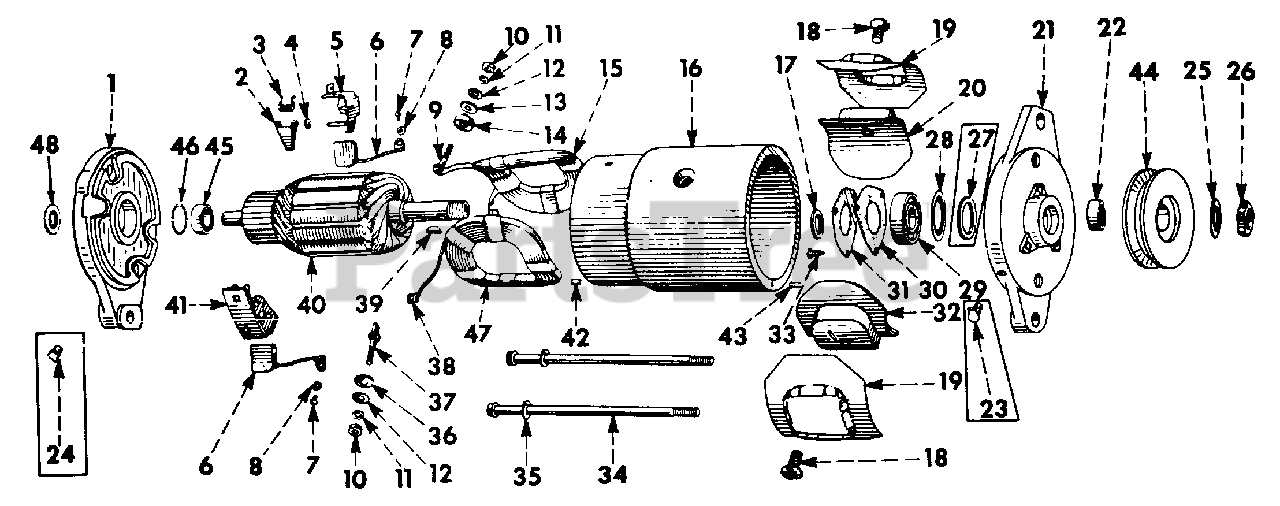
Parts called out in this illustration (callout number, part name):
1	Frame Assy, Commutator End
3	Spring, Brush
4	Washer, Brush Arm Space
5	Holder, Brush Ground
6	Brush
7	Screw, No. 6 X 1/4 C-Z Slt Rd Hd Mach
7	Screw, No. 6 X 5/16 C-Z Slt Rd Hd Mach
8	Washer, Brush Lead Attaching Screw Lock
9	Stud, Terminal Field
10	Nut, No. 12 C-Z
11	Washer, Field Terminal Stud Lock
12	Washer, Terminal Stud
13	Washer, Terminal Stud Insulating
14	Bushing, Field Terminal Insulating
14	Bushing, Field Terminal Insulating Inside
15	Coil, Field
16	Frame
17	Collar, Drive End Spacer - Inside
18	Screw, Pole Shoe
19	Insulator, Field Coil
20	Shoe, Pole
21	Frame, Drive End
22	Collar, Drive End Space
23	Not used in this application
24	Not used in this application
25	Washer, Drive End Shaft Nut Lock
26	Nut, Drive End Shaft
27	Not used in this application
28	Plate, Drive End Grease Slinger
29	Bearing, Drive End Ball
30	Gasket, Drive End Retainer Plate
31	Plate, Drive End Retainer
32	Shoe, Pole
33	Screw, Drive End Retainer Plate
34	Bolt, Thru
35	Washer, Thru Bolt
36	Bushing, Armature Terminal Insulating
37	Stud, Terminal Armature
38	Clip, Terminal to Brush
39	Key, No. 5 Woodruff Aly-Slt
40	Armature
41	Holder, Brush Insulated
42	Pin, Commutator End Dowel
43	Pin, Drive End Dowel
44	Pulley, Motor Generator
45	Bearing, Commutator End Ball
46	Clamp, Commutator End Bearing
47	Coil, Field
48	Plug, Commutator End Bearing Well
